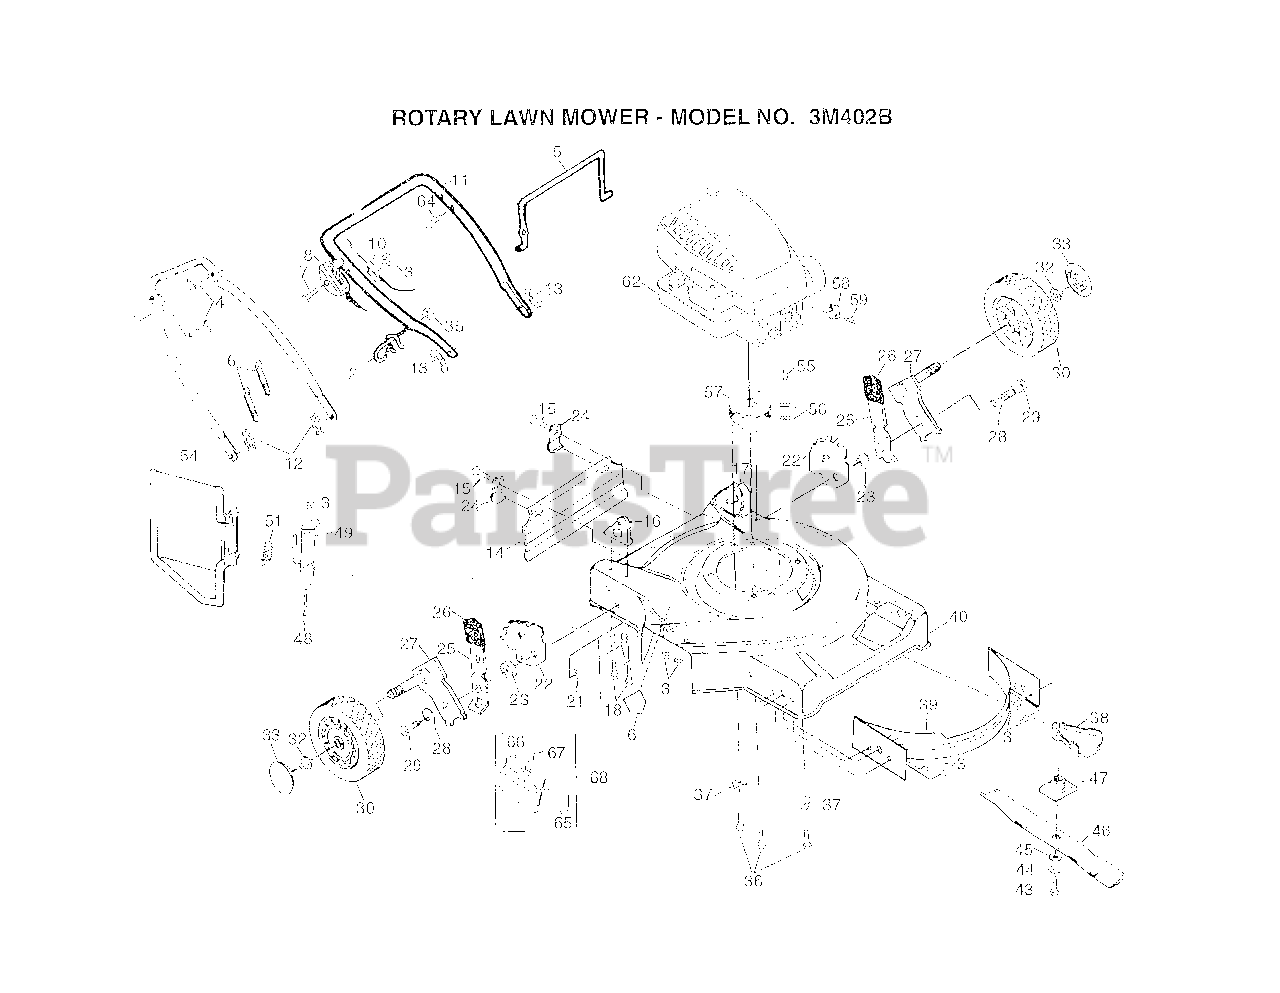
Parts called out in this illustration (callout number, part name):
2	ROPE GUIDE
4	BOLT.HANDLE.LM
5	CONTROL BAR
7	SCREW.HXHD.WASH.
8	"CONTROL, THROTTLE"
10	"CABLE,ENG ZONE CO"
12	HAIRPIN COTTER
13	"NUT,WING PM"
14	SKIRT.REAR.FGD.22
15	TAPPING SCREW
18	SCREW
19	STEEL WASHER
21	LOCKNUT PM
22	BRACKET.ADJ.9POS.
24	"BRKT,DEFL PM"
25	SPRING SELECTOR
26	KNOB PM
27	ARM.AXLE.ASM.BZP.
28	"WASHER, BELLEVIL."
29	BOLT SHLD 3/8-16
30	WHEEL.8X2.PR.RAD.
32	HEX FLANGE LOCKNT
33	HUB CAP
35	NUT
36	SCREW
39	BAFFLE FRONT 22SD
40	KIT.HSG.22SD.FWGD
43	SCREW
44	LOCKWASHER
45	"WASHER,HARDEN"
46	"BLADE.MULCH.22"""
47	ADAPTOR.BLADE.LM
48	ROD.HINGE.COMBI-C
49	BRACKET.HINGE.W/F
54	GUARD.DISCH.22SD.
55	HI PRO KEY PM
56	SCREW
57	ENGINE.PULLEY.FWG
58	CABLE CLAMP
59	SCREW PM
61	DECAL HYT
64	"SCREW,PAN HD"
66	BAIL.PLUG.MUL.22.
68	KIT.MULCHER.PLUG.22SD
